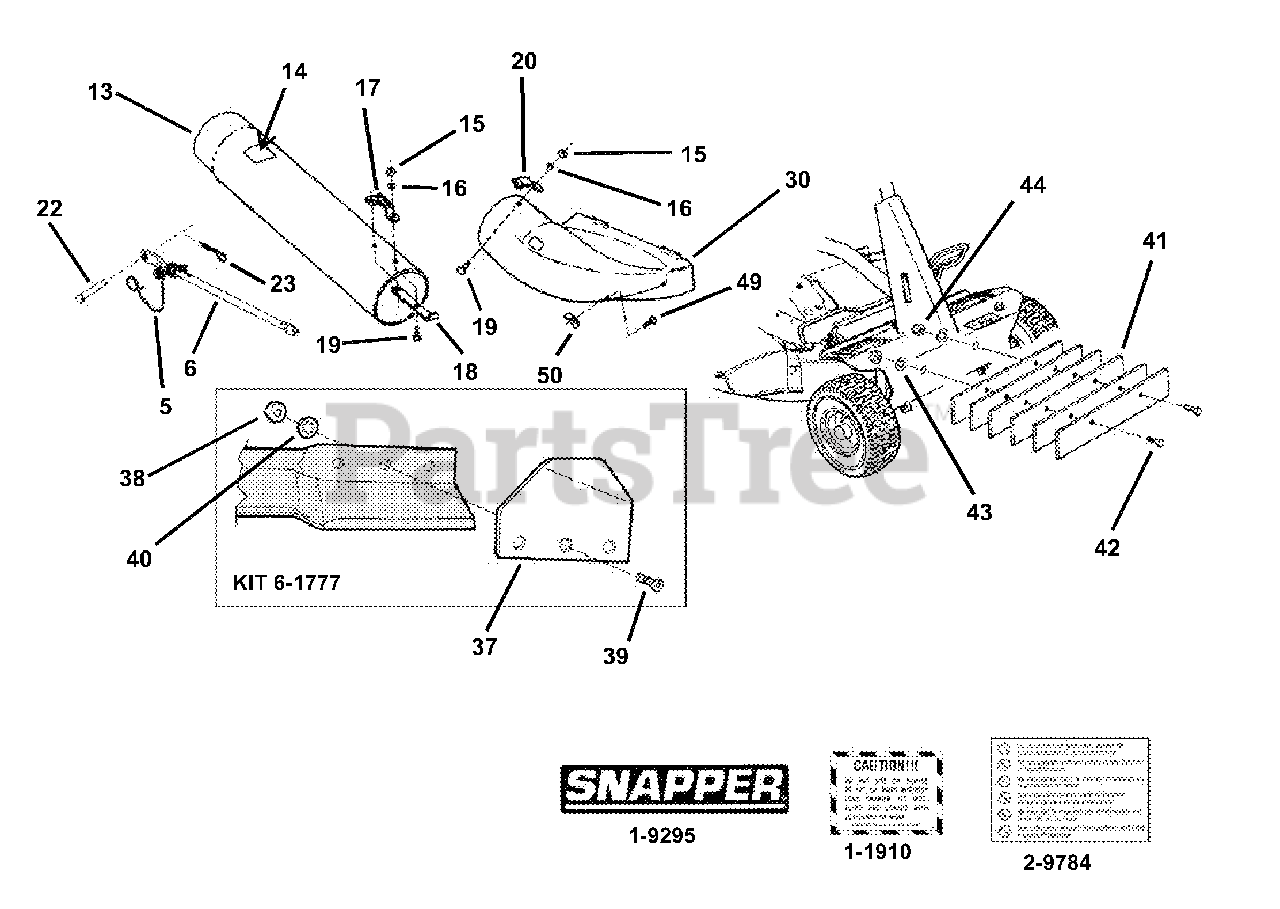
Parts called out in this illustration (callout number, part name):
1-1910	DECAL, GRASS CATCHER
1-9295	DECAL, SNAPPER
2-9784	DECAL, DECK / CHUTE INT'L
5	ASSY, Spring & Hook
6	BRACE, Rear (24-1/2" Long)
13	TUBE, Grass (36" long)
14	DECAL, Caution
15	NUT, 1/4-20 Hex
16	WASHER, 1/4 I.T.Lock
17	HANDLE, Tube
18	BASE, Tube Handle
19	BOLT, 1/4-20 x 3/4" Carriage
20	LATCH, Tube Chute
22	PIN, 5/16 x 11/16" Clevis
23	PIN, 3/32 x 1-1/2" Hair
30	ADAPTER, 28" & 33"
37	LIFT, Air
38	NUT, 5/16-24 Hex
39	SCREW, 5/16-24 x 21/32
40	WASHER, 5/16" I. T. Lock
41	WEIGHT, Front Frame
42	SCREW, 5/8-11 x 1-3/4" Cap
43	WASHER, 5/8 Split Lock
44	NUT, 5/8-11 Hex
49	BOLT, 5/16-18 x 1" Carriage
50	WING LOCKNUT, 5/16-18
